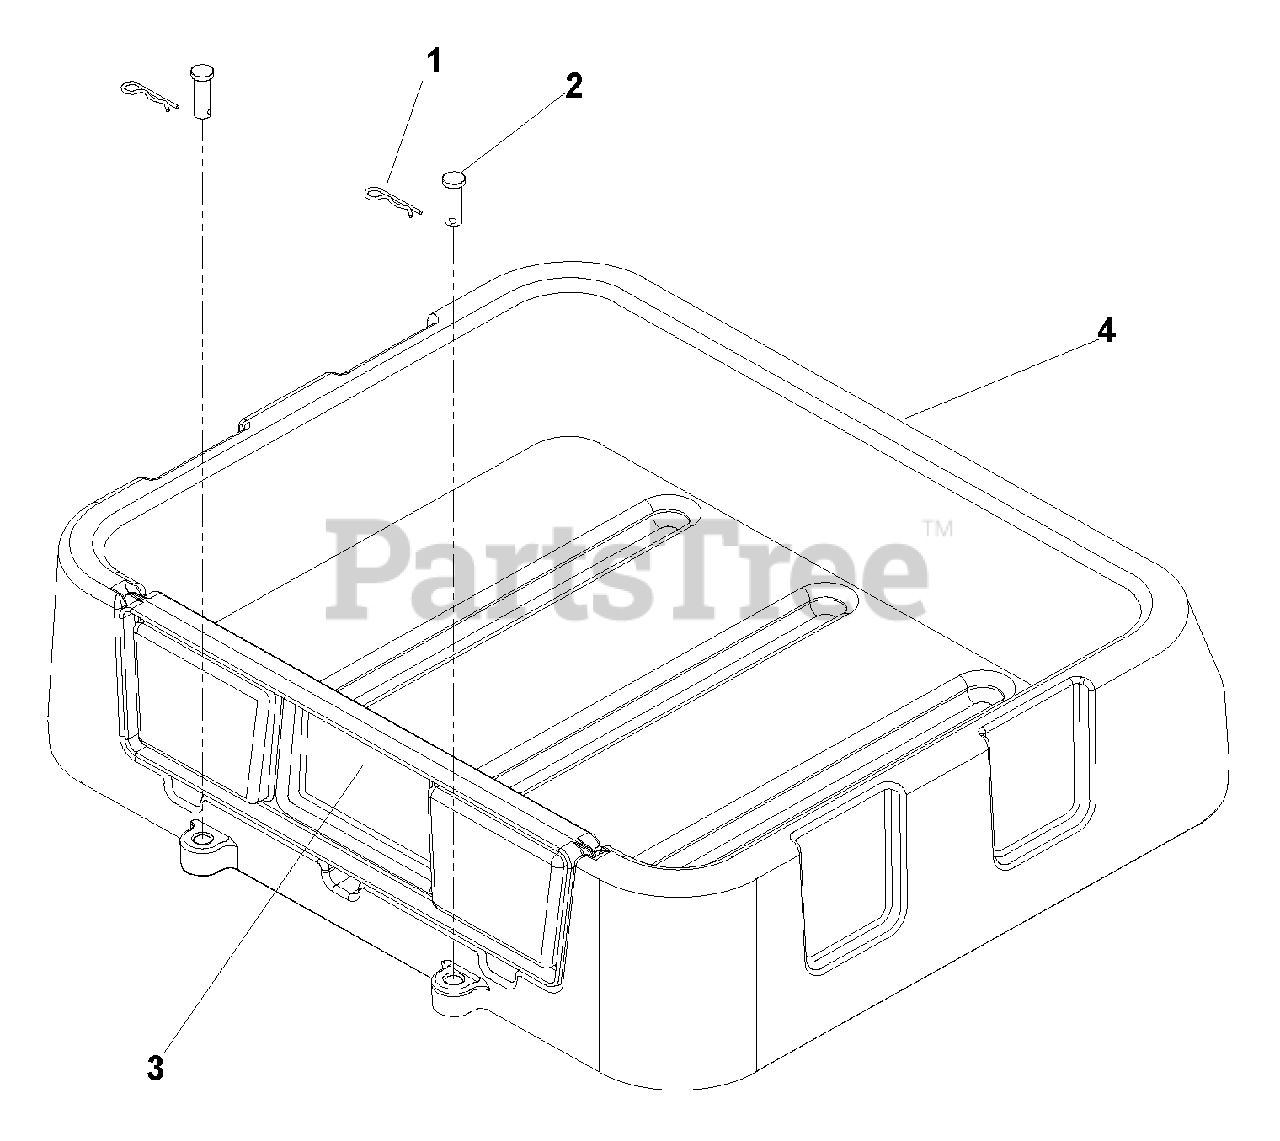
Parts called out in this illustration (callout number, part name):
1	PIN, HAIR
2	PIN, CLEVIS
4	UTILITY BOX
